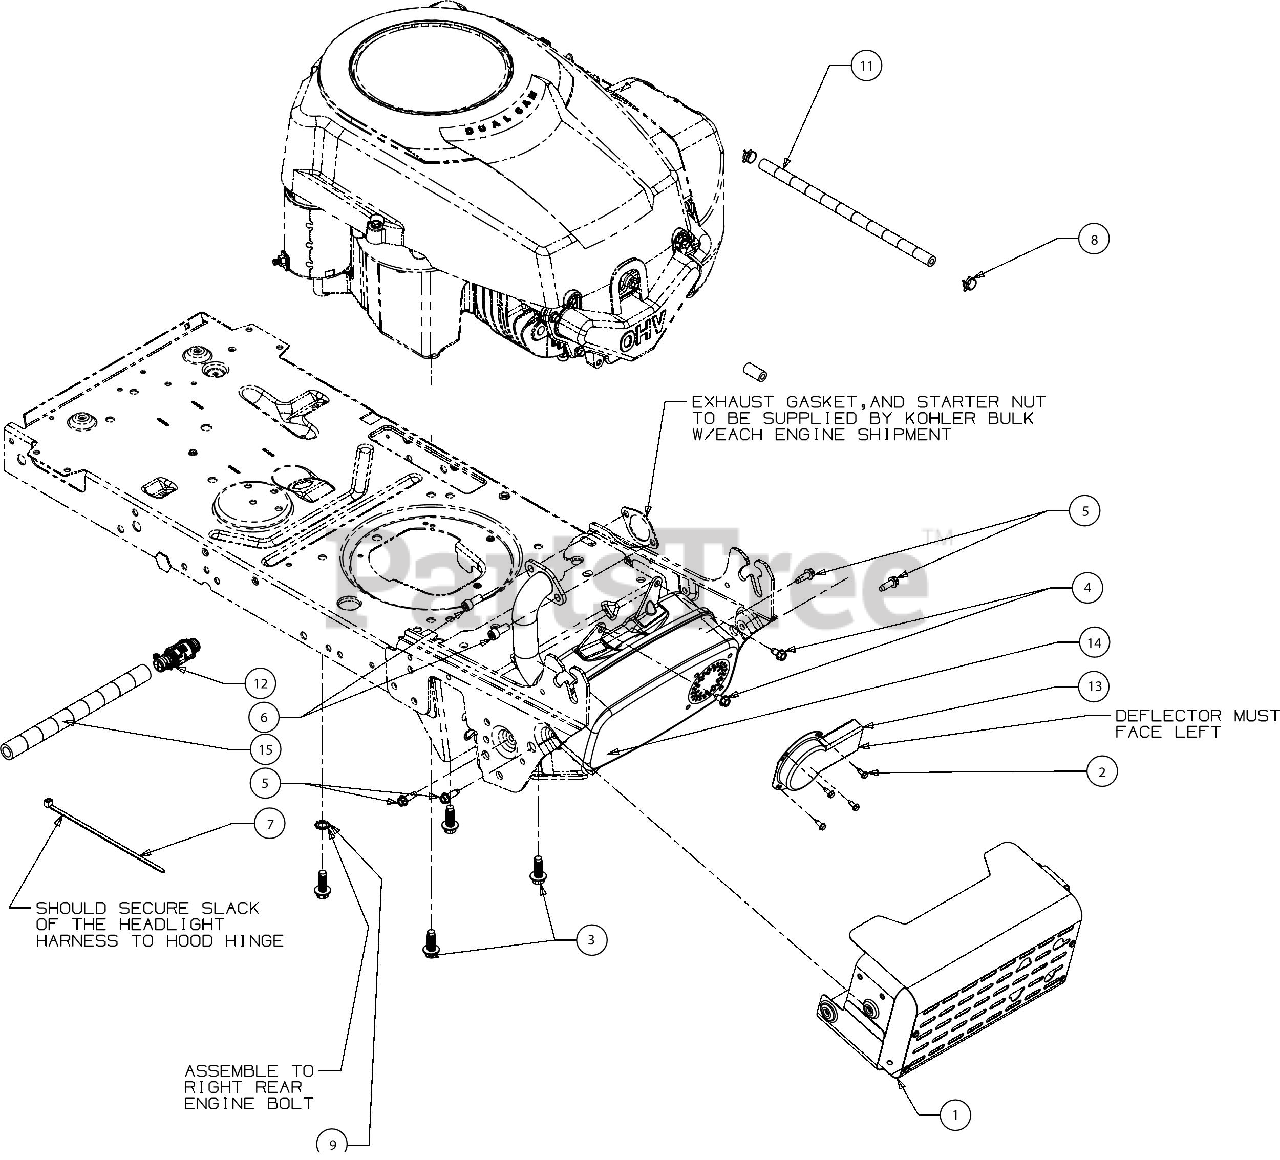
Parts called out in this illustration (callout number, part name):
2	HEX SCREW WASHER HD #8-18 X 0.500
3	SCREW 3/8-16 X 1
4	SCREW 1/4-20 X.500
5	SCREW 1/4-20 X .750
7	CABLE TIE 7"
8	HOSE CLAMP 1/20
9	LOCK WASHER 3/8
11	FUEL HOSE LOW PERMEATION
12	OIL DRAIN VALVE
13	EXHAUST DELECTOR
15	DRAIN HOSE 14''
